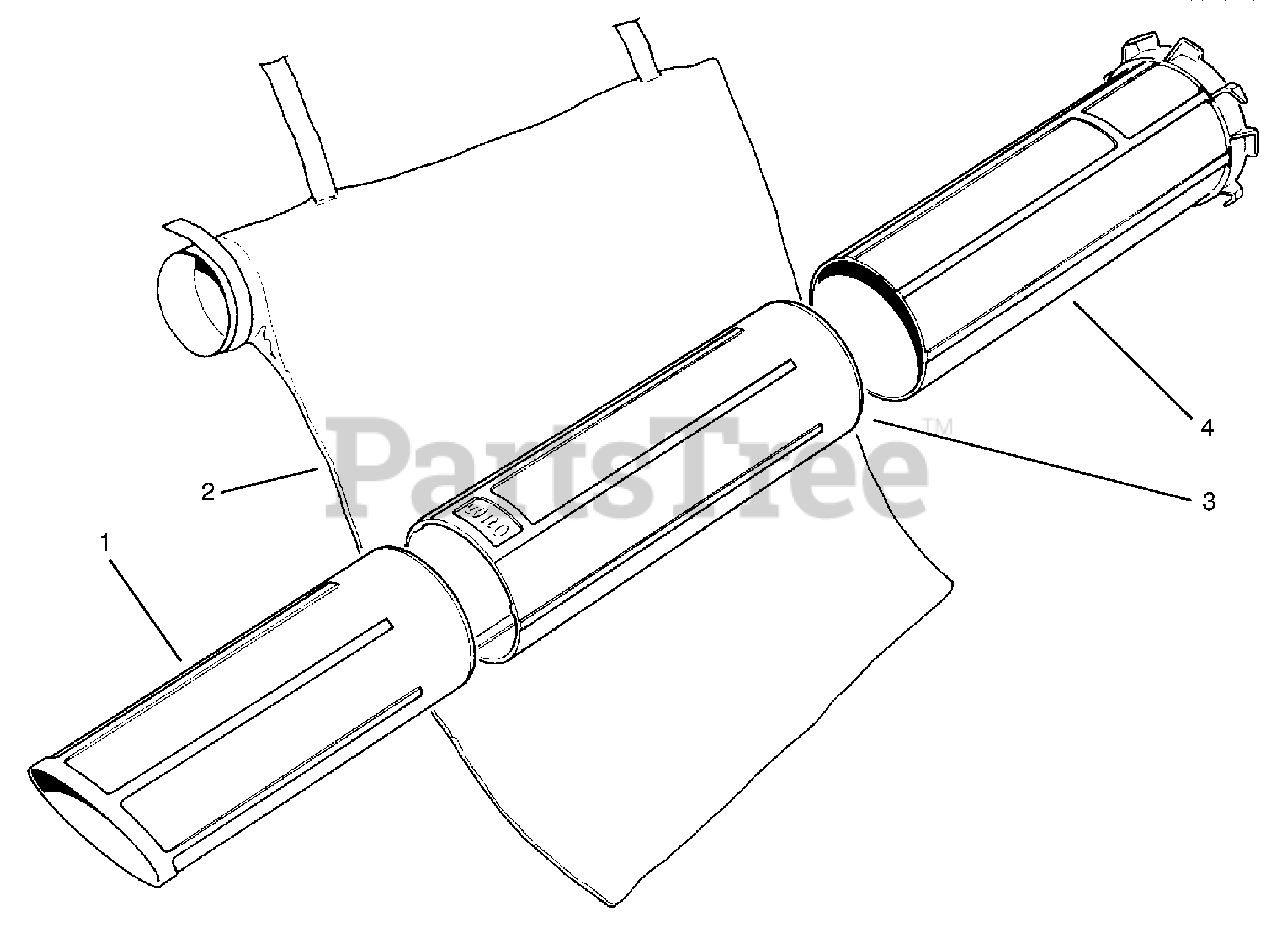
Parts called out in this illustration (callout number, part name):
1	Tube-Vacuum, Lower
2	Bag-Vacuum
3	Tube-Vacuum, Middle
4	Tube-Vacuum, Upper
